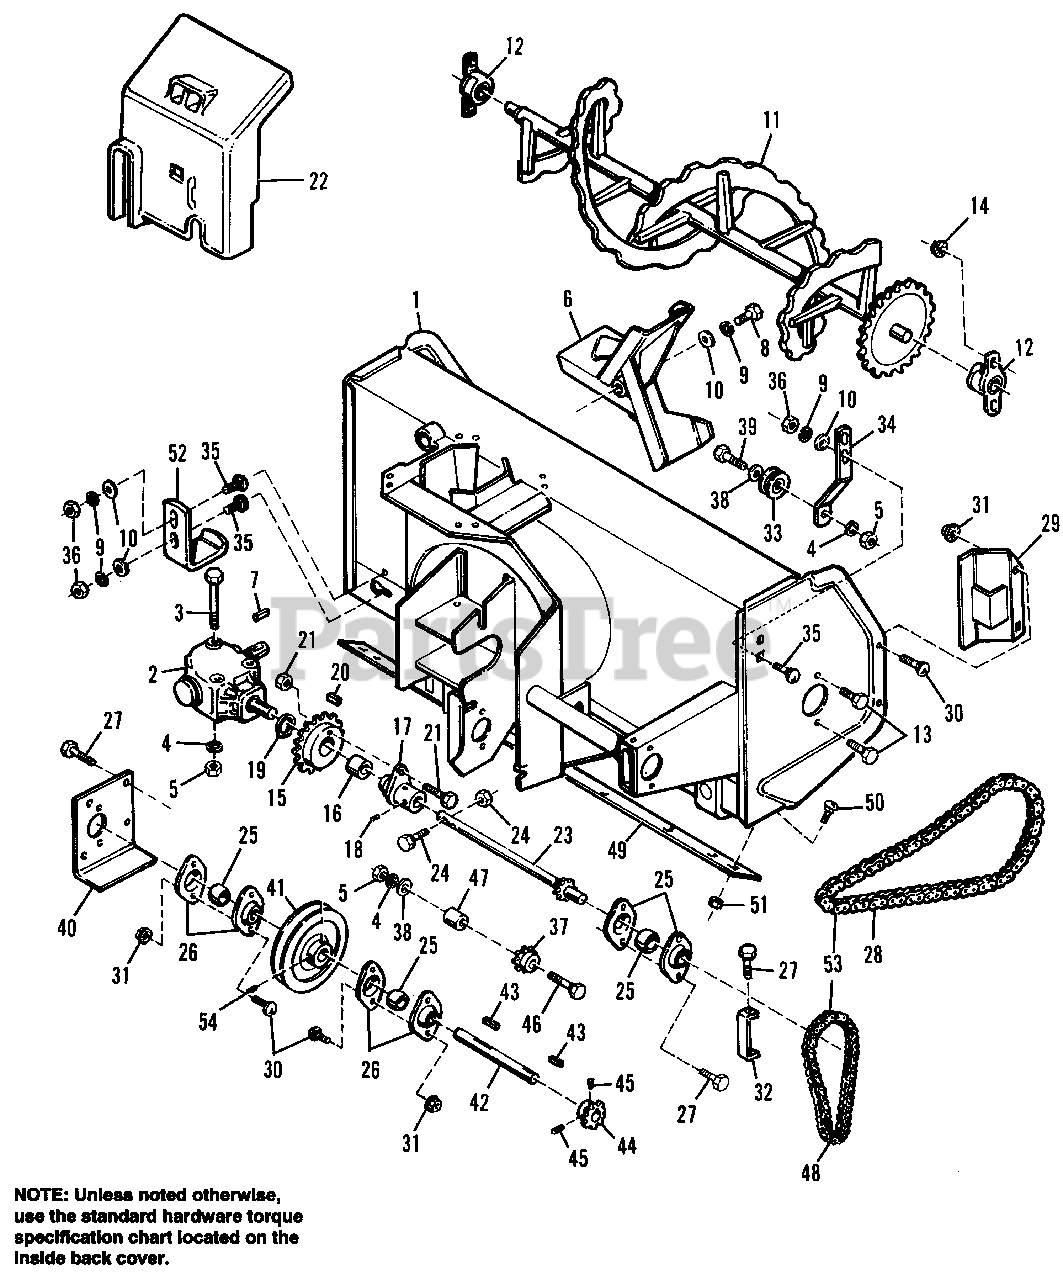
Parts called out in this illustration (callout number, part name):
1	FRAME ASSY.
3	CAPSCREW, Hex, 3/8-16 x 4, Gr. 5
4	LOCKWASHER, 3/8
5	NUT, Hex, 3/8
7	KEY, 8mm x 7mm x 35mm
8	CAPSCREW, Hex, M8-1-1/4 x 25mm
9	LOCKWASHER, 5/16
10	WASHER, Plain, 5/16
12	BUSHING, Side Mount
13	SCREW, Lock, Flange, Whizlock, 3/8-16 x 3/4
14	NUT, Hex, Flange, 2-Way Lock, 3/8-16
17	SHEAR PLATE
18	SETSCREW, Hex, Socket Cup Pt., 5/16-18 x 5/16
19	SNAP RING, External
20	KEY, 8mm x 35mm
21	SHEAR BOLT, Fan, w/Nylon Nut, 5mm x .8 x 40mm
22	COVER, Reduction, Plastic
23	SHAFT, Driven
24	SHEAR BOLT, Auger, w/Nylon Nut, 1/4-20 x 2
26	BEARING, Flange
27	SCREW, Lock, Flange Whiz, 5/16-18 x 1/2
28	CHAIN, #40 x 91 Links (without connecting link)
29	GUARD, Chain, Auger
30	CARRIAGE BOLT, 5/16-18 x 5/8
31	NUT, Hex, Flange, 2-Way Lock, 5/16-18
32	GUARD, Chain, Drive Shaft
33	PULLEY, Idler
34	ARM, Chain Adjuster
35	CARRAIGE BOLT, 5/16-18 x 1
36	NUT, Hex, 5/16-18
37	SPROCKET, Idler
38	WASHER, Plain, 7/16
39	CAPSCREW, Hex Hd., 3/8-16 x 1-3/4
40	PLATE, Support Bearing
41	PULLEY ASSY. (Incl. Ref. No. 54)
42	SHAFT, Driving
43	KEY, 3/16 x 3/16 x 1
45	SETSCREW, Hex, Socket, 1/4-20 x 5/16
46	CAPSCREW, Hex Hd., 3/8-16 x 2-3/4
47	SPACER, Idler
48	CHAIN, #40 x 40 Links (Incl. Ref. No. 53)
49	EDGE, Cutting
50	CARRIAGE BOLT, 5/16-18 x 3/4
51	NUT, Hex, Centerlock, 5/16-18
53	MASTER LINK, Chain #40
54	SETSCREW, Pulley
